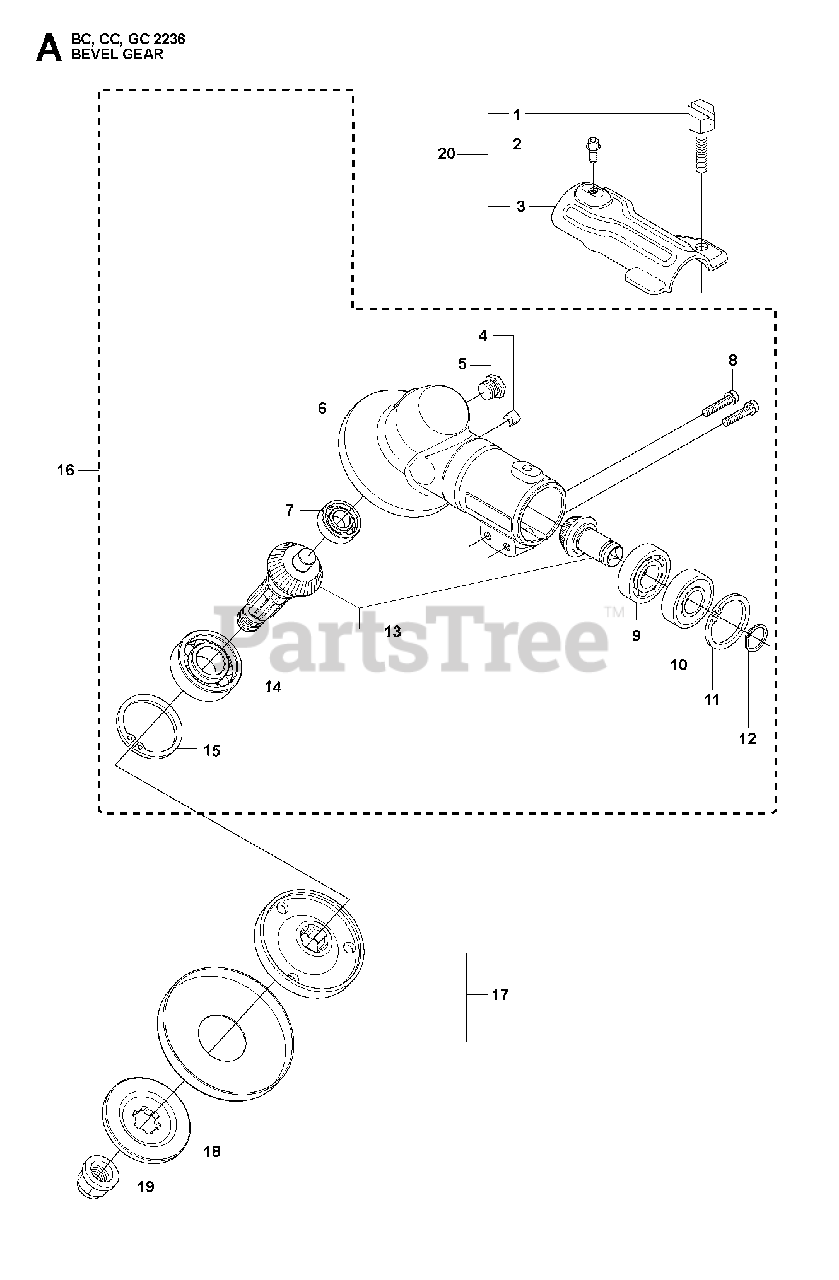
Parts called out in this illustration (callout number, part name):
1	SCREW
2	SCREW
3	RP HOLDER
4	MAGNET
5	PLUG
6	GEAR CASE
7	BALL BEARING 24X9X1/609ZR
9	BALL BEARING
10	BALL BEARING
11	RETAINING RING SGH 28
12	SEEGER CLIP
13	SPARE PARTS KIT
14	BALL BEARING
15	RETAINING RING
16	GEAR COMPLETE
16	%GEAR CASE ASSY
17	RP CARRIER
18	RP FLANGE
19	NUT BLADE
20	CLAMP
